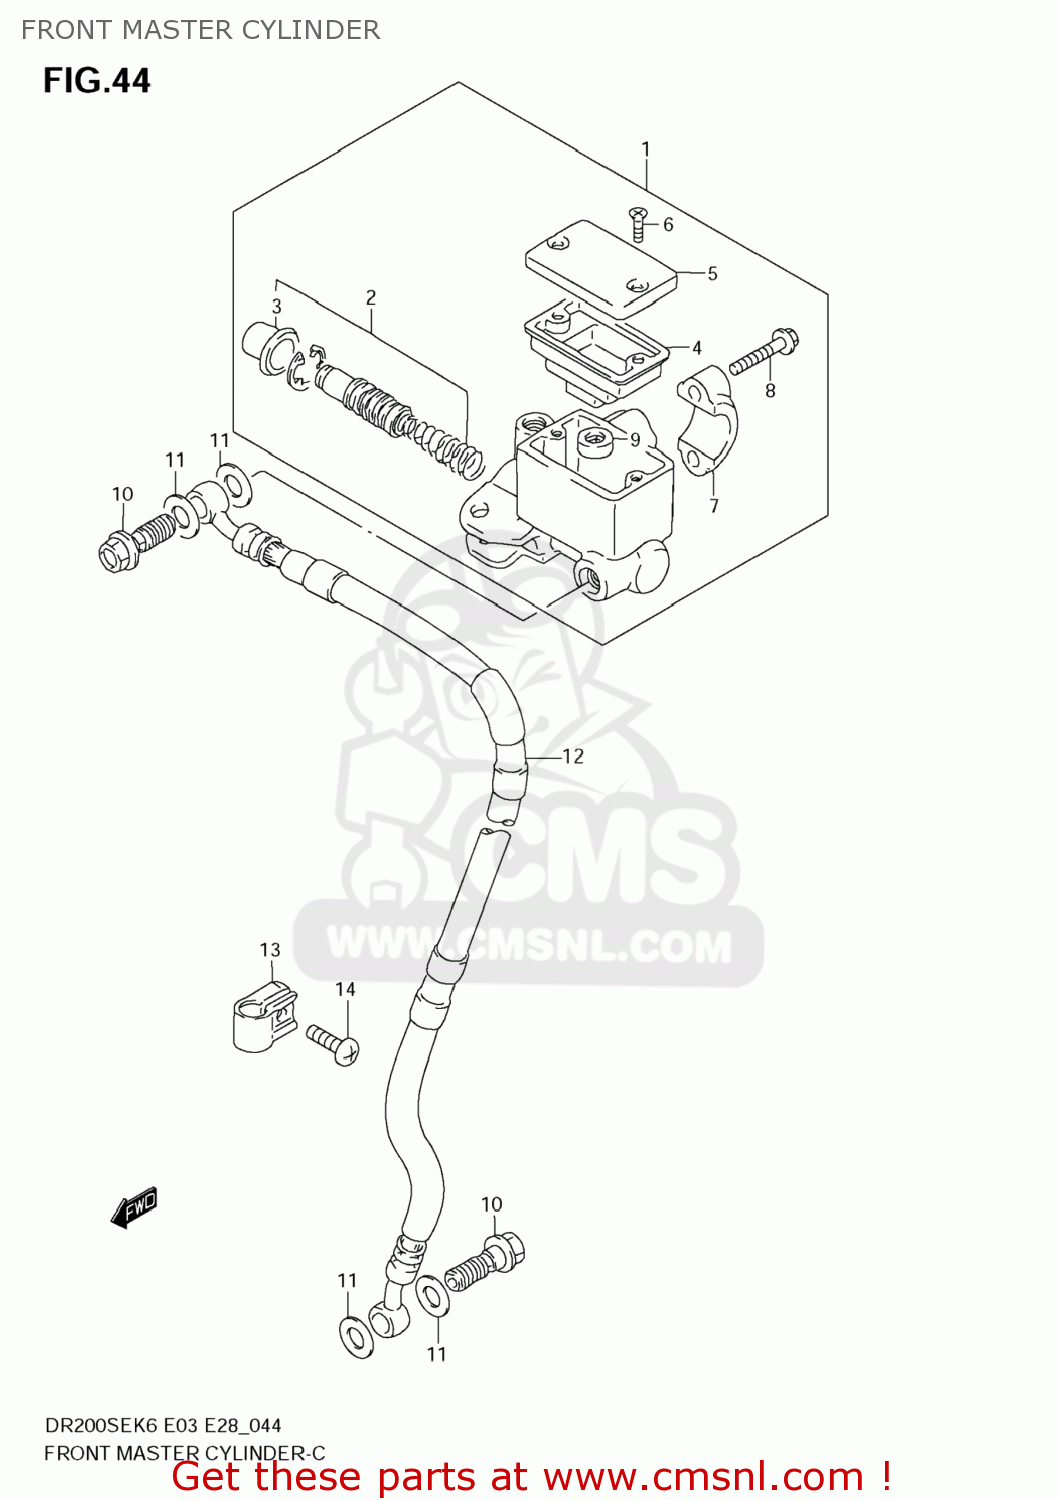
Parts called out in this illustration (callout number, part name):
1	CYLINDER ASSY,FR MASTER
2	PISTON/CUP SET
3	BOOT
4	DIAPHRAGM
5	CAP
6	SCREW
7	HOLDER
8	BOLT
9	SEPARATOR
10	BOLT UNION
11	WASHER(10X15X1.5)
12	HOSE,FR BRAKE
13	CLAMP,BRAKE HOSE
14	SCREW
